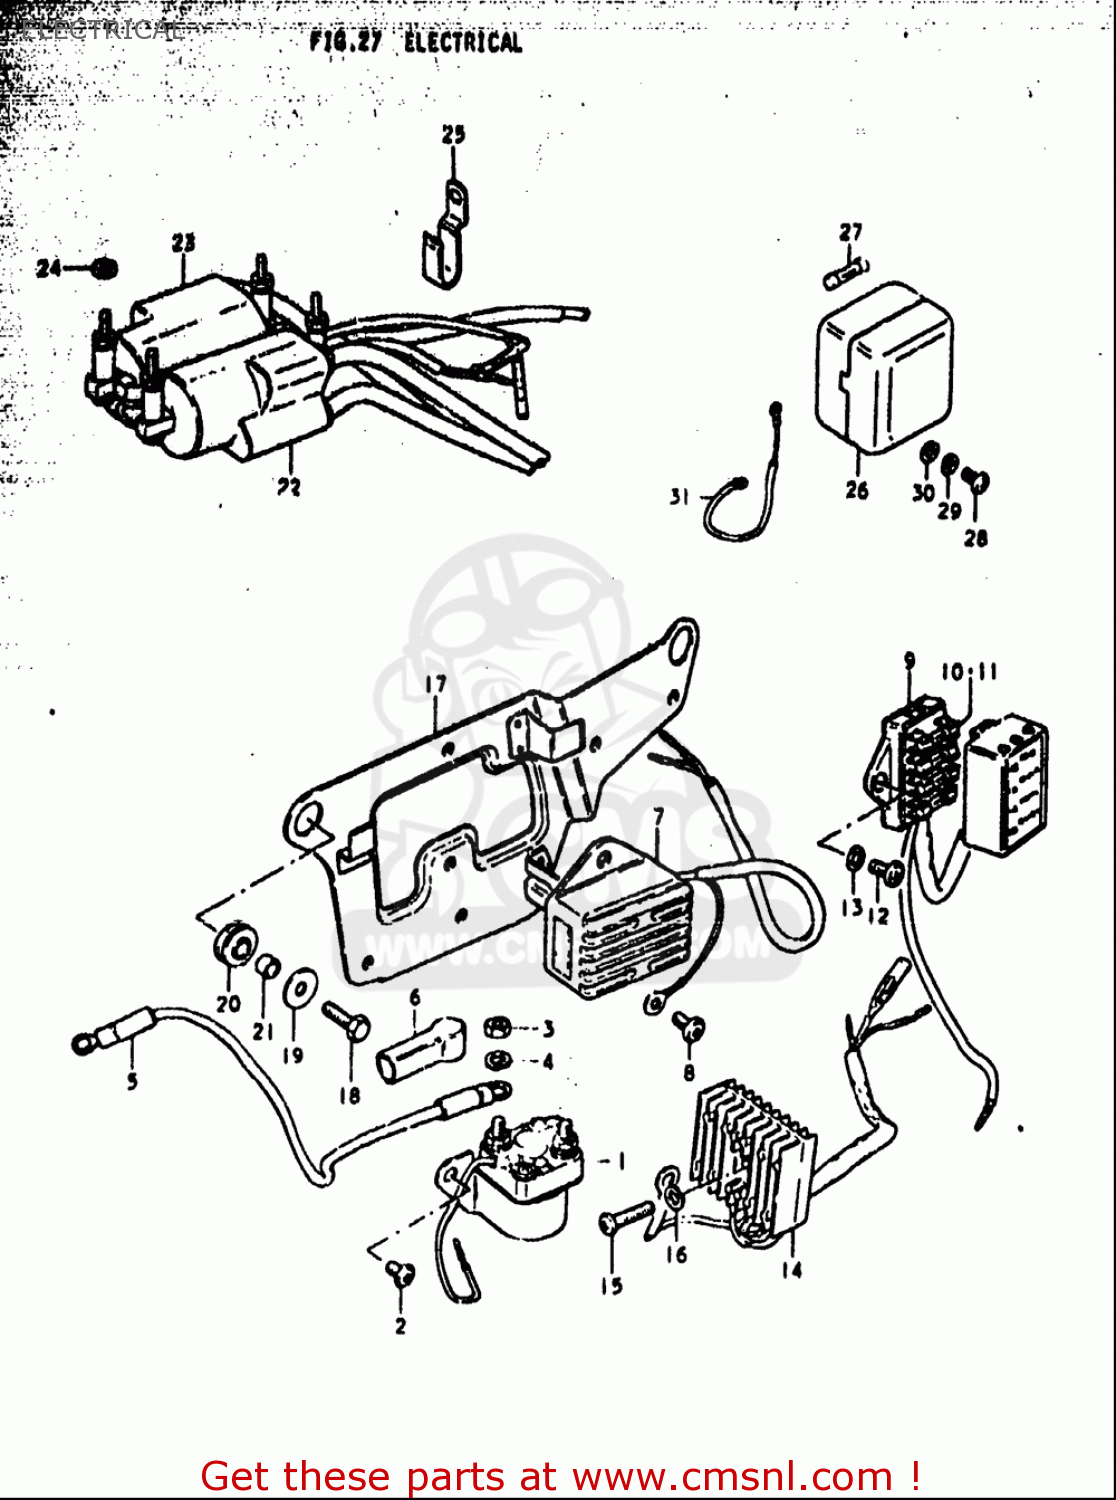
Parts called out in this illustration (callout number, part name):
1	RELAY ASSY,STARTING MOTOR
2	SCREW
3	NUT
4	WASHER,LOCK
5	LEAD WIRE,BATTERY(-)
6	CAP,STARTER MOTOR LEAD
7	REGULATOR ASSY,VOLTAGE
8	SCREW
9	BOX ASSY,FUSE
10	FUSE(10A)
11	FUSE(15A)
12	SCREW
13	WASHER
14	RECTIFIER ASSY
15	SCREW
16	WASHER,LOCK
18	BOLT
19	WASHER(6.5X22X1.6)
20	CUSHION
21	SPACER(6.2X8.3X5.7)
22	COIL ASSY,IGNITION
23	COIL ASSY,IGNITION
24	NUT
25	CLAMP
27	FUSE(10A)
28	SCREW
29	WASHER,LOCK
30	WASHER
